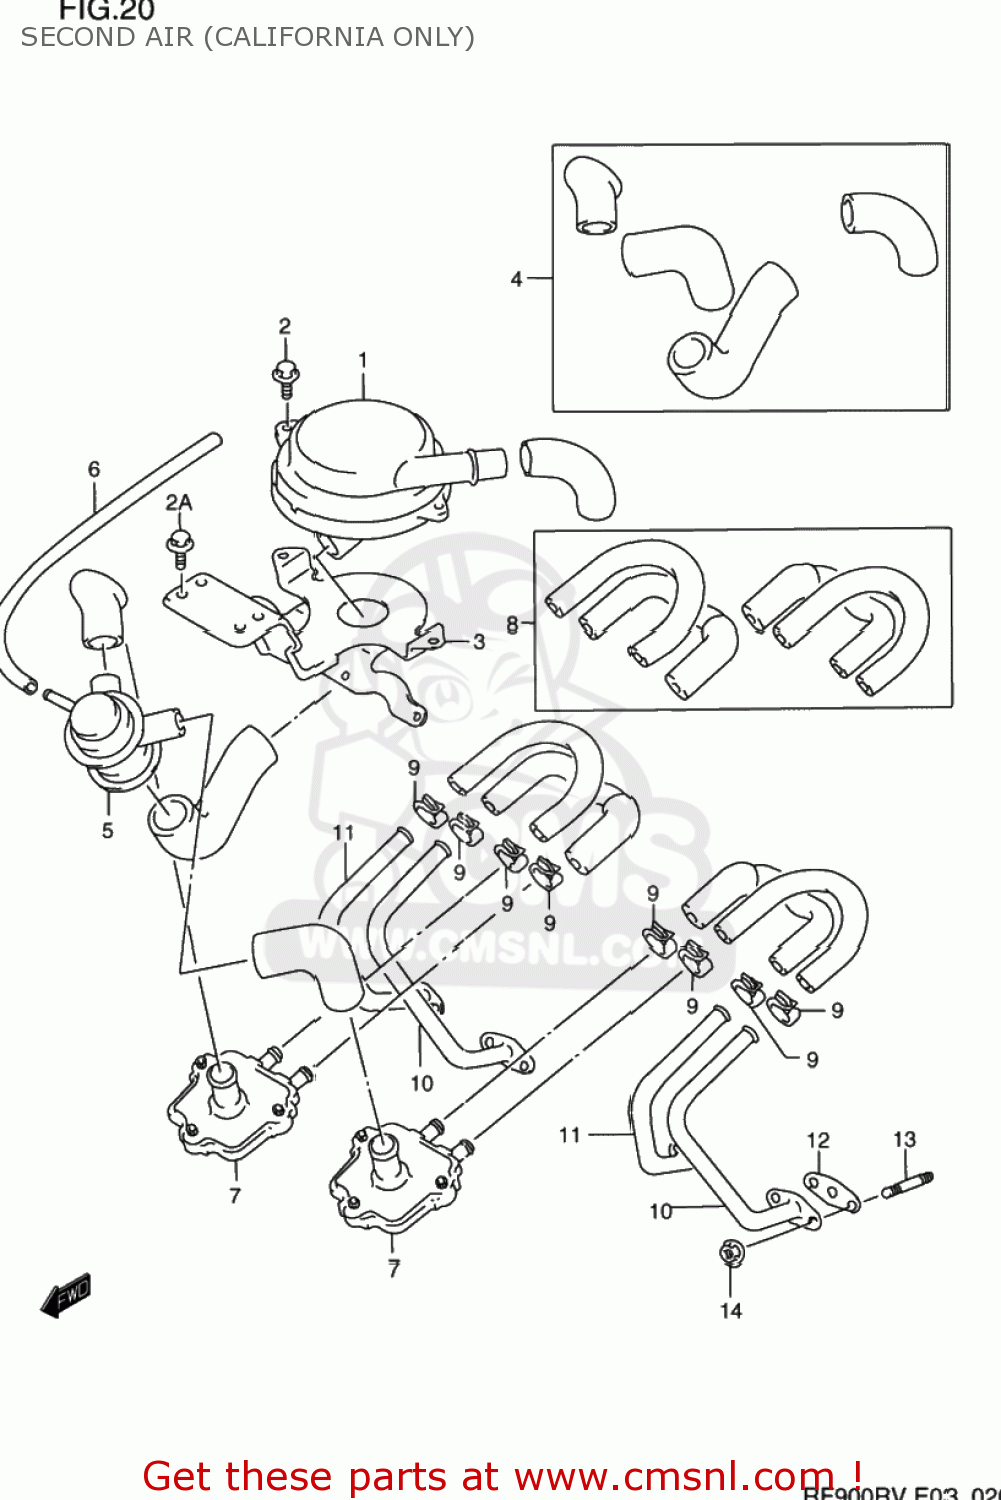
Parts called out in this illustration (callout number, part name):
1	CLEANER ASSEMBLY,SECOND AIR
2	BOLT
2A	BOLT
3	BRACKET COMP,SECOND AIR
4	HOSE SET,2ND AIR NO.2
5	VALVE ASSEMBLY,SECOND AIR SWITCH
6	HOSE(4.5X8.5X600)
7	VALVE ASSY,2ND AIR REED
8	HOSE SET,2ND AIR NO.1
9	CLIP
10	PIPE COMP,SECOND AIR NO.1
11	PIPE COMP,SECOND AIR NO.2
12	GASKET,SECOND AIR PIPE (N (NAS)
13	STUD BOLT
14	NUT
